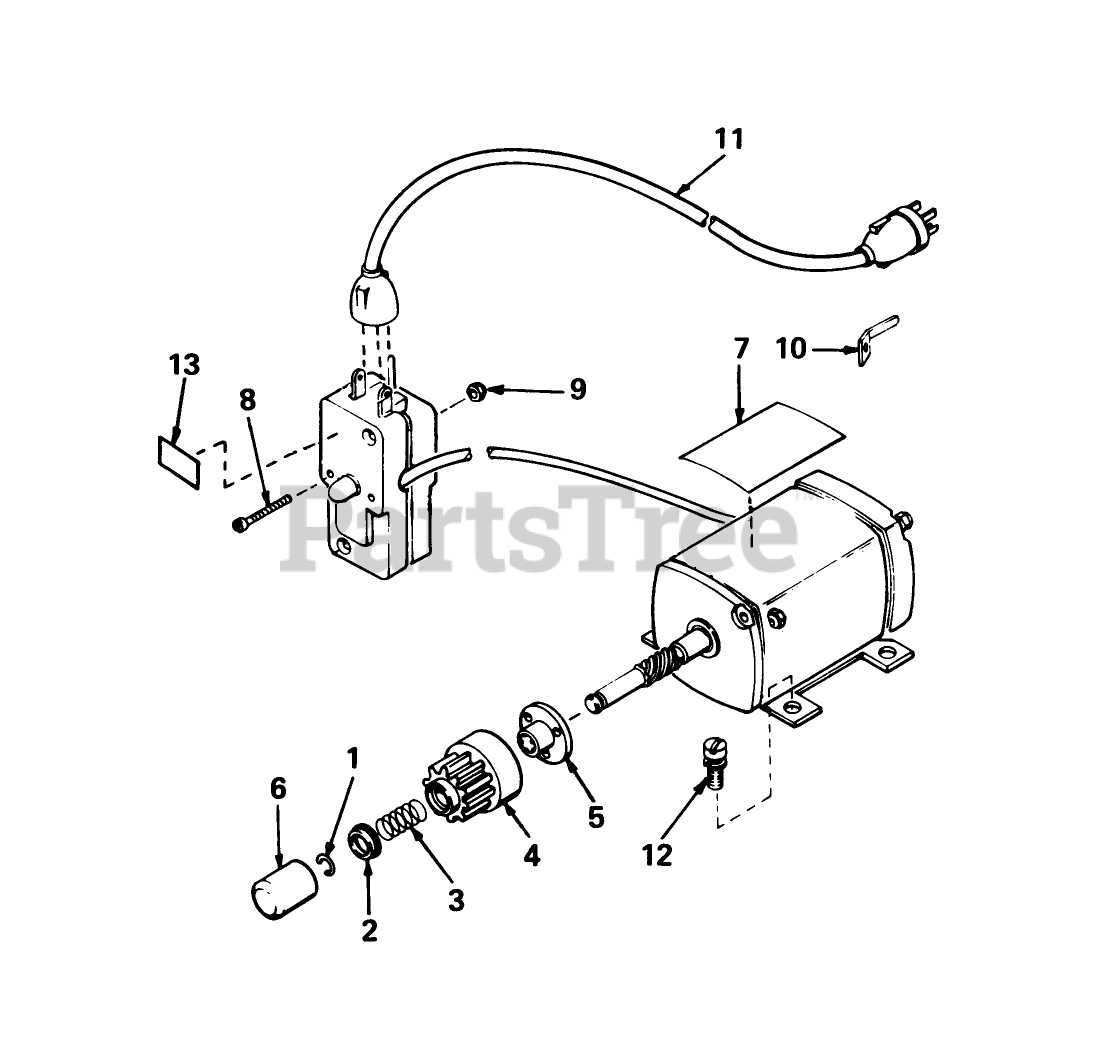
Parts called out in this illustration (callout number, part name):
1	Ring-Retainer
2	Retainer-Spring
3	Spring-Anti Drift
4	Gear
5	Nut-Engaging
6	Cover-Dust
7	Decal
8	Screw, Pan Hd.
9	Nut Lockwasher
10	Clip
11	Cord-Extension
12	Screw
13	Decal
